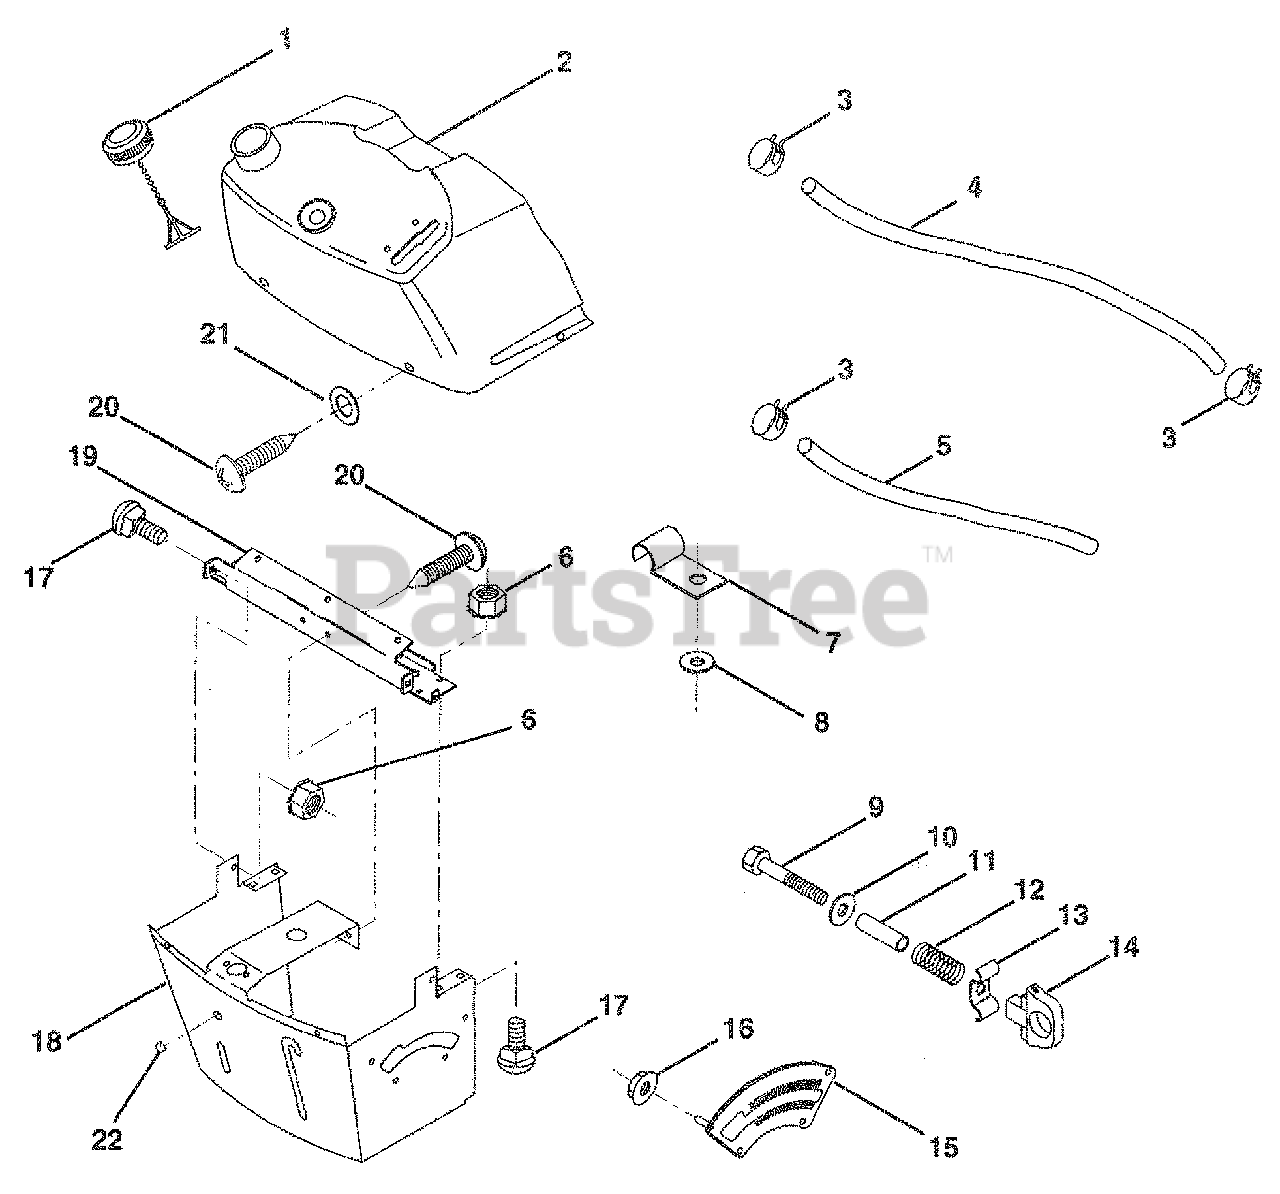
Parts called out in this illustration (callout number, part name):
1	Cap, Fuel
2	Assembly, Dash & Fuel Tank
3	Clamp, Hose
4	Line, Fuel
6	Nut/Hex, Keps 1/4-20
7	Clip, Fuel Line
8	Washer 9/32 x 3/4 x 16 Ga.
9	Bolt, Hex, Fin 1/4-20 x 1-3/4
10	Washer 11/32 x 11/16 x 16 Ga,
11	Spacer, Split
13	Clip, Height Adjustment
14	Knob, Height Stop
15	Adjustment, Quadrant Height
16	Nut, Self-Threading 3/16-18
17	Bolt, Carriage 1/4-20 x 1/2 Gr. 5
18	Support Assembly, Dash
19	Brace, Cross
20	Screw 1/4-20 x 1/2 SLFTTPG
21	Washer 9/32 x 1/2 x 16 Ga.
